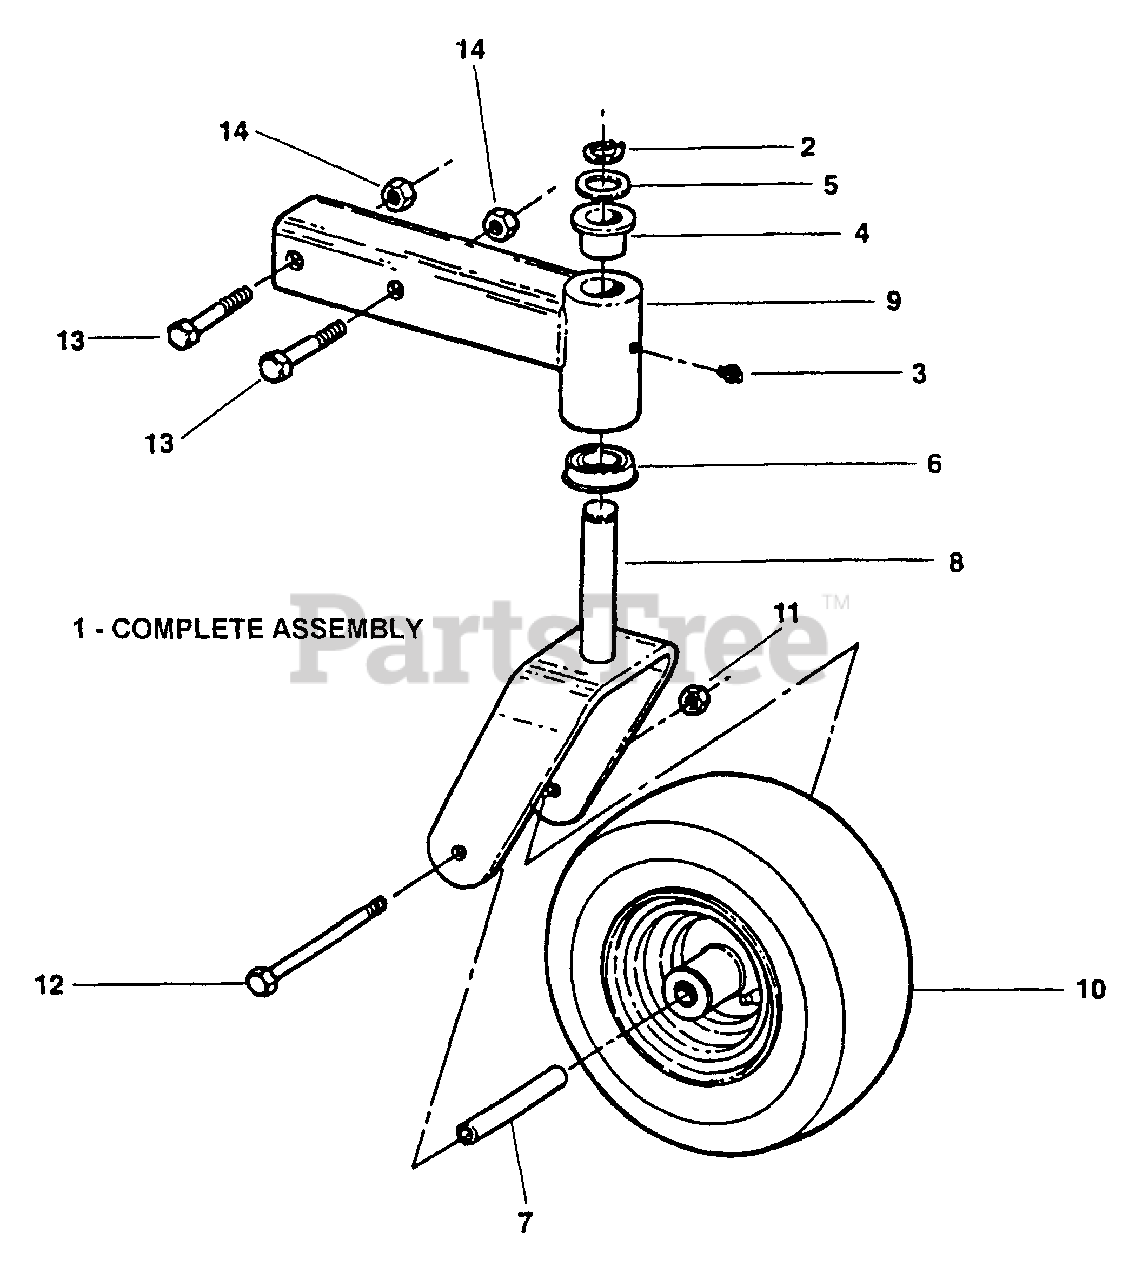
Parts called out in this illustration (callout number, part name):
1	ASSEMBLY, 11" Front Caster
2	RING, 1" External Retaining
3	LUBE FITTING, Straight (press-fit for .187 dia. Hole)
4	BUSHING, Caster
5	BUSHING, 1" Machine
6	BEARING, Flanged Ball
7	TUBE, 5/8" O.D. x 18 Gage Wall x 3.545 Long
8	YOKE, Caster (Weldment)
9	ARM, Telescoping Caster (Weldment)
10	ASSEMBLY, Wheel
11	NUT, 7/16-14 Hex Head Cap
12	SCREW, 7/16-14 x 6" Hex Head Cap
13	BOLT, 1/2-13 X 3" GD5 CZ
14	NUT, 1/2-13 HEX NYLON LOCK
